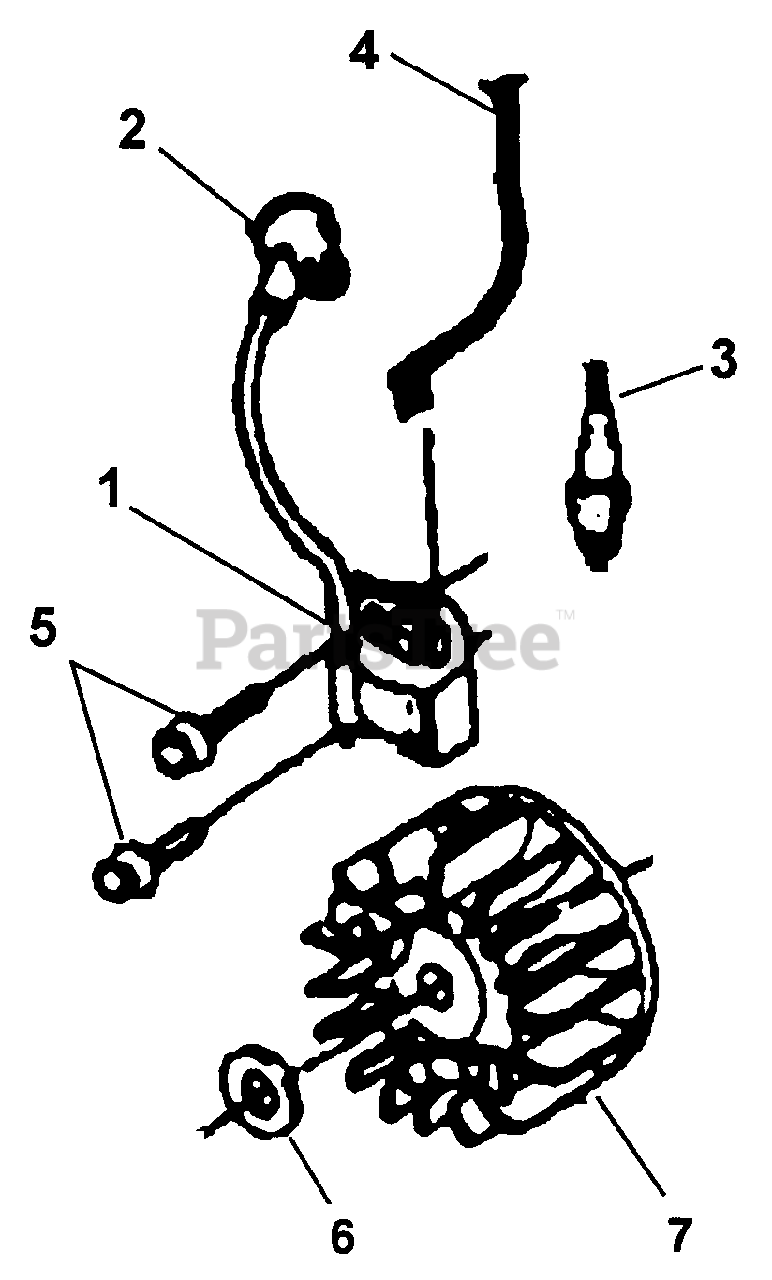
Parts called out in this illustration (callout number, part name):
1	IGNITION KIT
2	TERMINAL & COVER
3	SPARK PLUG
4	LEAD, ELECTRICAL
5	SCREW, SELF TAP. 8-32 X 1"
6	WASHER, FLAT
7	ROTOR
